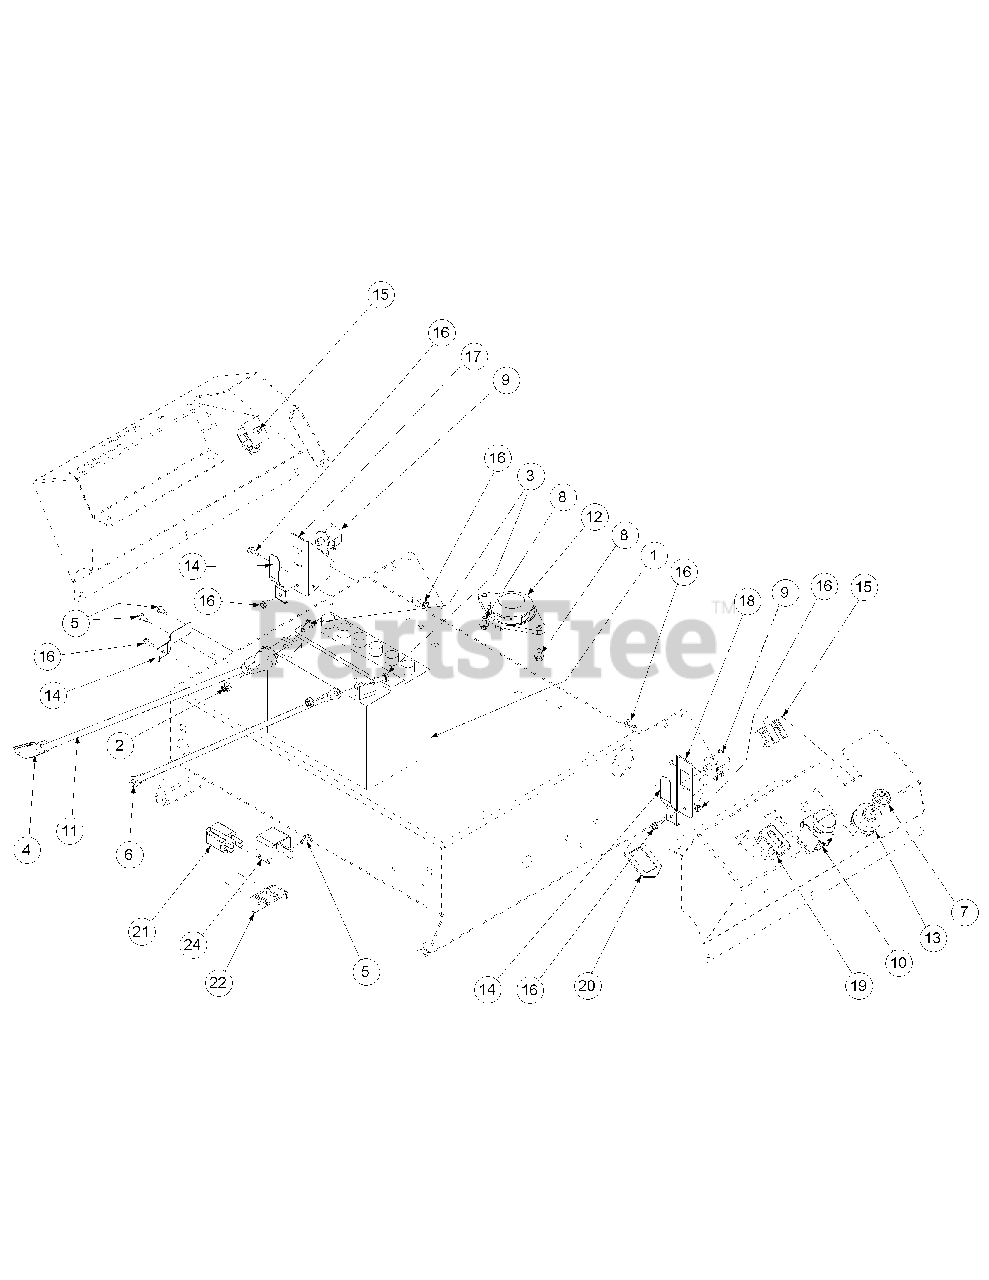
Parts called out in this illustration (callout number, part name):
1	Battery, 12V 225CCA 30Min
2	Lock Nut, Nylon Insert, 1/4-20
3	Hex Cap Screw, 1/4-20 x .75
4	Boot, 1" OD Rubber Battery-PST Red
5	Self Tapping Screw, 12-24
6	Cable, Battery, Black, 17"
7	Nut, 5/8-32, w/Cap
8	Self Tapping Screw, 1/4-20 x 1/2
9	Normally Closed Safety Switch
10	Electric PTO Switch
11	Cable, Battery, Red, 24"
12	Normally Closed Seat Switch
13	Switch, Ignition, 6 Pin
14	Safety Switch Retainer Spring
15	Neutral Switch
16	Self Tapping Screw, 10-32 x 1/2
17	Bracket, Safety Switch, Left Hand
18	Bracket, Safety Switch, Right Hand
19	Hour Meter
20	PTO Switch Bracket
21	Switch, Plunger
22	Control Housing Assembly
24	Switch, Clamp
